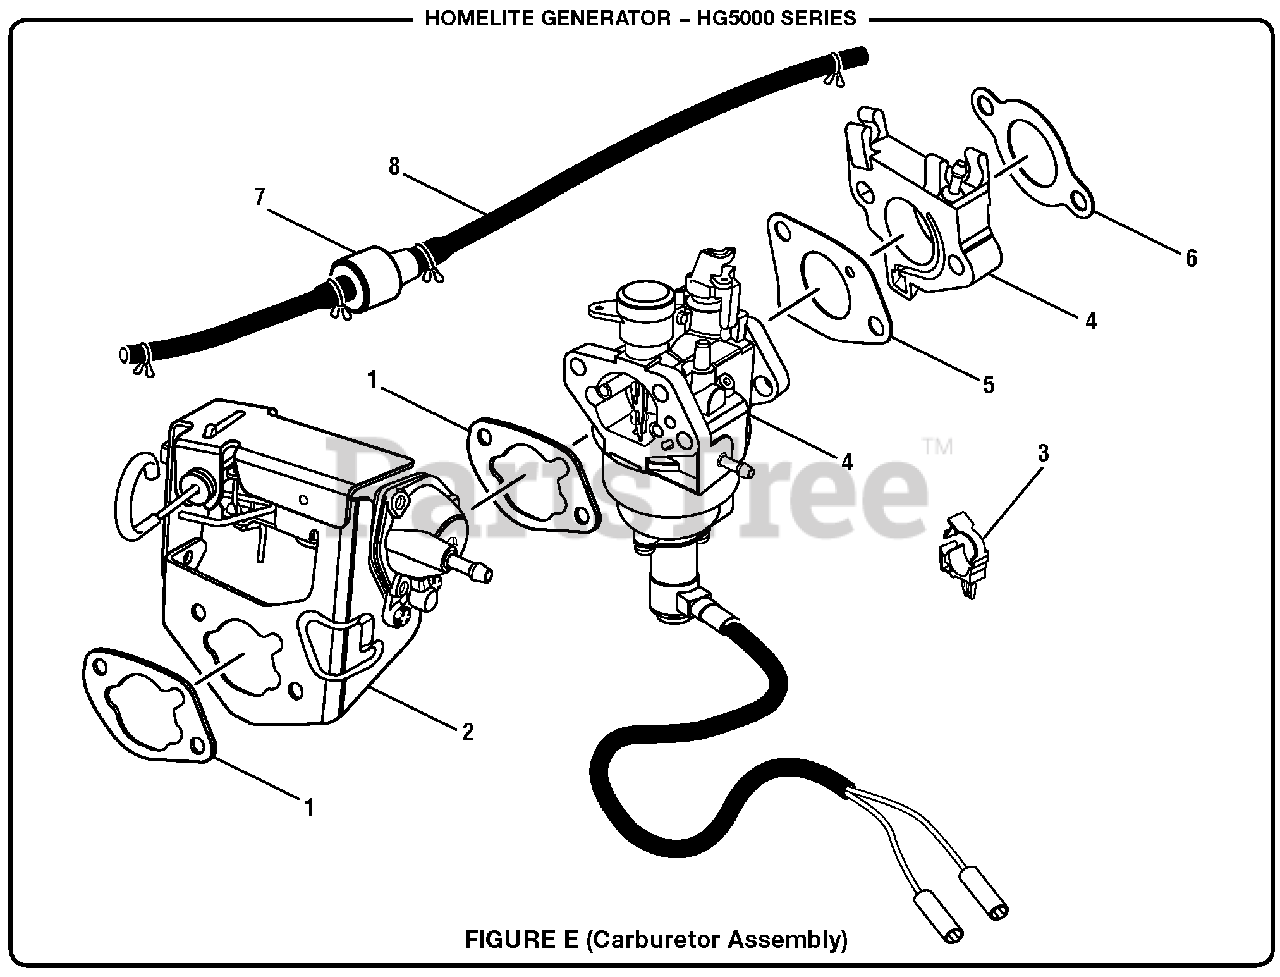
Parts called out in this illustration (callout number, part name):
1	Air Cleaner Gasket
2	Choke Assembly
3	Fuel Line Clamp (Holder)
4	Carburetor Assembly
5	Carburetor Gasket
6	Carburetor Inlet Gasket
7	Check Valve
8	Check Valve Assembly
